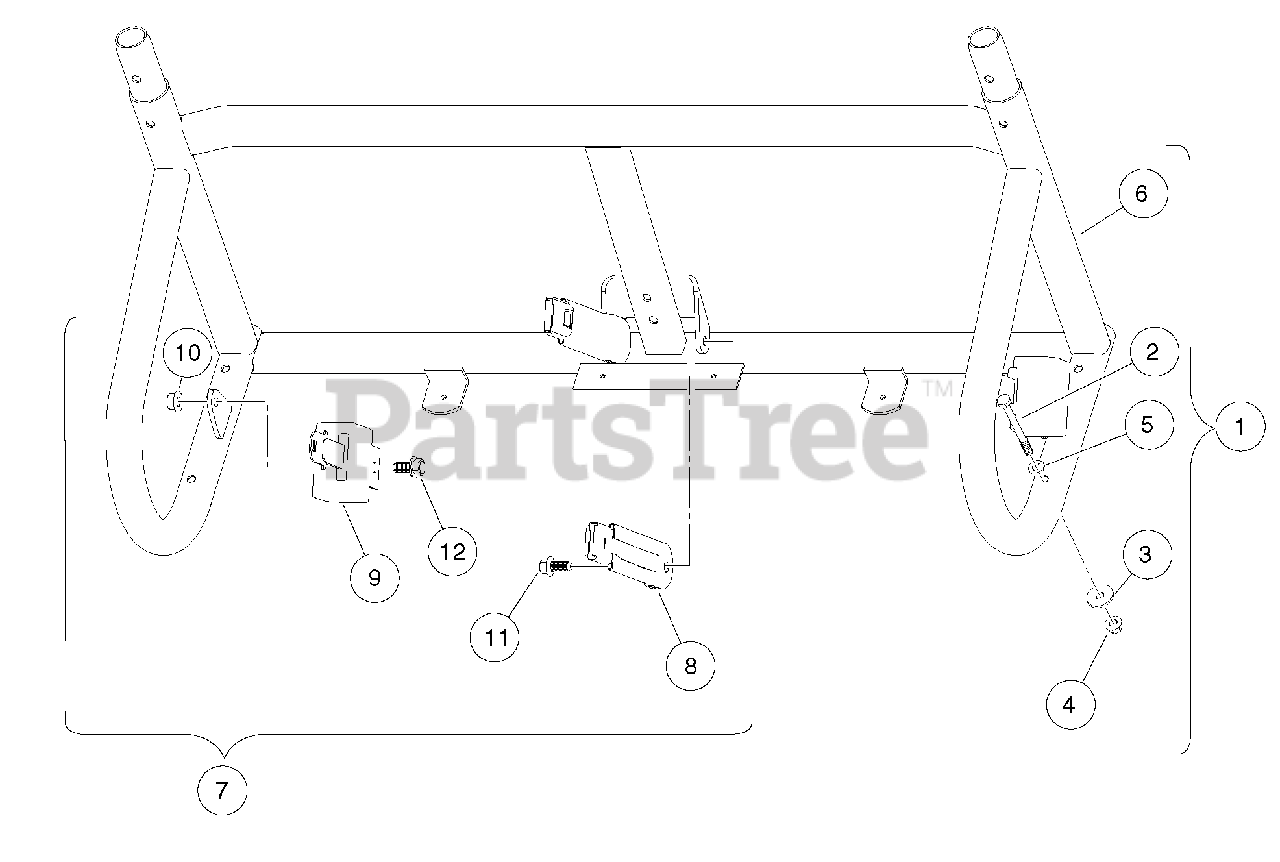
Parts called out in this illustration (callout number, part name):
1	Instl, Rops, Lower
2	Bolt, M10x1.50x100 (Black)
3	Washer Hard,m10
4	Nut Flg M10 X 1.5 Mech Def
5	Washer, Hard, M10, Zn-Ni/Blk
6	Weldment,seat Support,hs,rops
7	Instl, Seat Belt, Restyle
8	Buckle, Seat Belt with Sleeve
9	Retractor, Seat Belt
10	Ln Flg, M12 X 1.75, Md, Black
11	Screw,m12x1.75x30 Thd Form Blk
12	Bolt Flg, M12x1.75 X 25 Black
